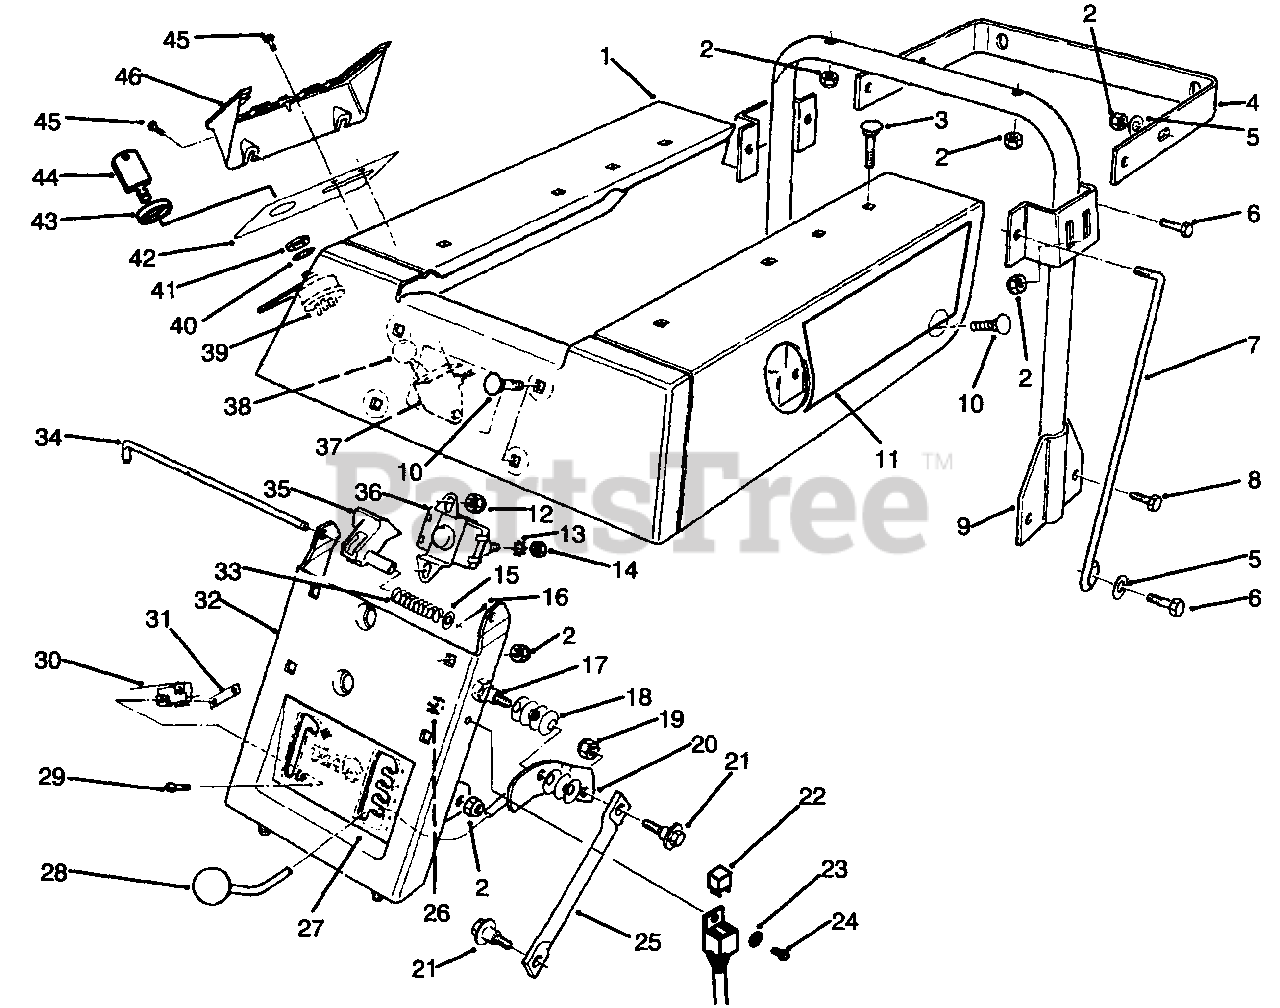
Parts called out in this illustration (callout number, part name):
1	Body W.A.-Rear
2	Nut-Lock
3	Bolt-Carriage
5	Washer-Flat
6	Screw-Cap Hex. Hd.
7	Brace-Support, Seat
8	Screw-Cap Hex. Hd.
9	Support W.A.-Seat
10	Bolt-Carriage
11	Decal-Lawn-Boy L.H.
12	Nut-Lock
13	Washer-Lock, Int. Tooth
14	Nut-Jam
15	Washer-Flat
16	Pin-Cotter
17	Bolt-Shoulder
18	Washer-Belleville
19	Nut-Lock
20	Handle W.A.-H.O.C.
21	Bolt-Shoulder
22	Relay
23	Washer-Flat
24	Screw-Cap Mach. Hd.
25	Link-H.O.C.
26	Nut-Lock
27	Decal-H.O.C. & Deck Engagement
29	Screw-Phil. Head
30	Switch-Micro
31	Nut-Double
32	Support W.A.-Seat
33	Spring-Prop, Seat
34	Rod-Base, Seat
35	Prop-Seat
36	Solenoid
37	Control-Throttle
38	Knob
39	Switch-Ignition (Incl. Ref. #40, 41 & 43)
40	Washer-Lock, Int. Tooth
41	Nut-Hex.
42	Decal-Panel, Control
45	Screw-Hex. Hd. Tapping
46	Cover-Panel, Control
